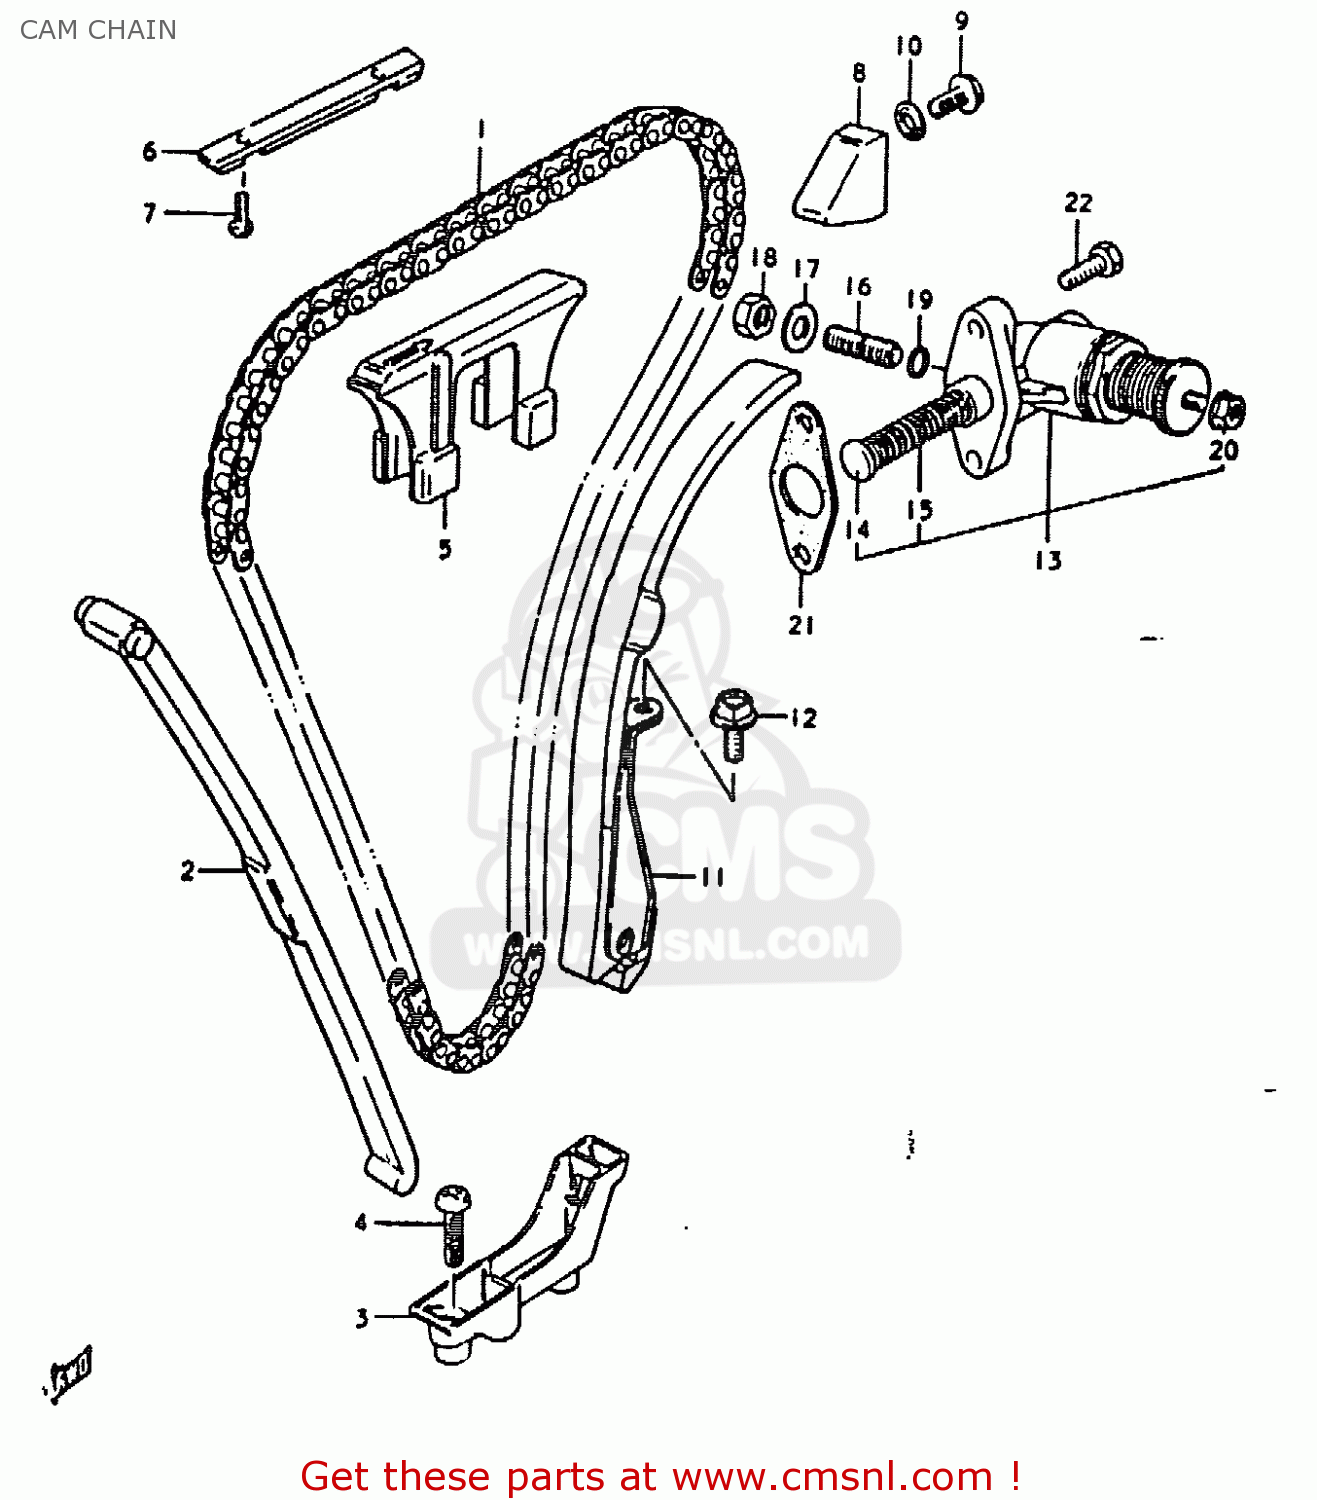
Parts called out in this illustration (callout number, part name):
1	CHAIN,CAMSHAFT DRIVE
2	GUIDE,CAM CHAIN
3	HOLDER,CAM CHAIN GUIDE
4	SCREW
5	GUIDE,CAM CHAIN NO.2
6	GUIDE,CAM CHAIN NO.3
7	SCREW
8	GUIDE,CAM CHAIN
9	BOLT
10	GASKET (NAS)
11	TENSIONER,CAM CHAIN
12	BOLT
13	ADJUSTER ASSEMBLY,TENSIONER
14	ROD,PUSH
15	SPRING
16	SCREW
17	WASHER
18	NUT
19	O-RING
20	NUT
21	GASKET,TENSIONER ADJUSTER (MCA)
22	SCREW
